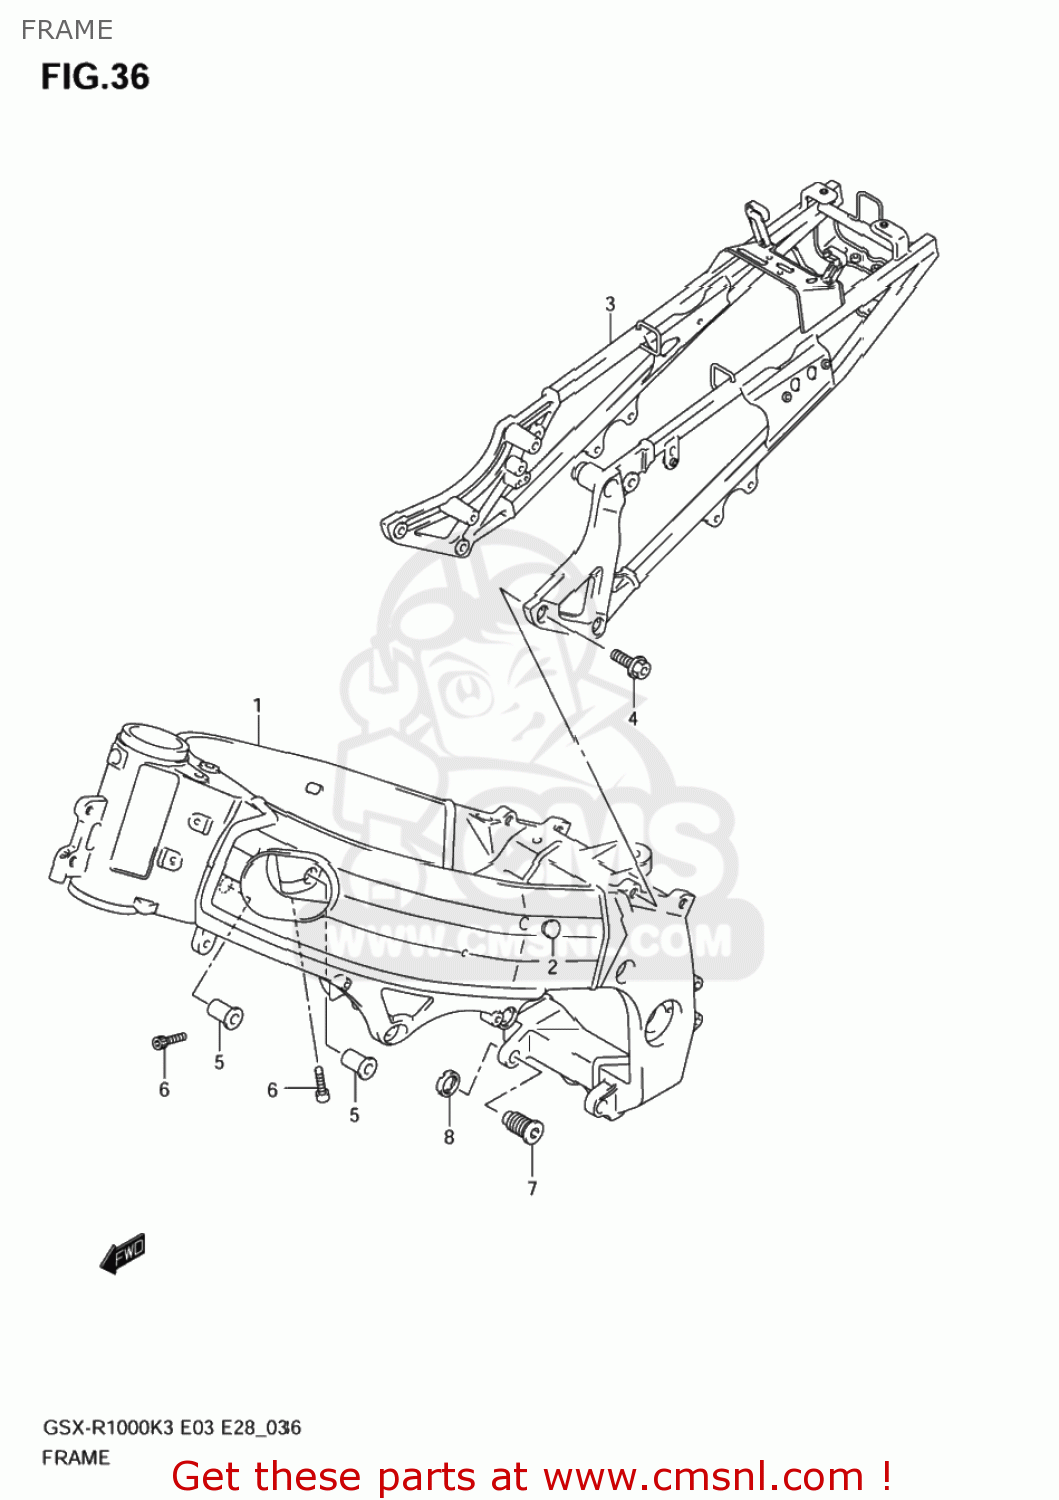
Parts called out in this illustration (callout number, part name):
1	FRAME COMP
2	CAP,TANK RAIL
3	RAIL,SEAT(BLACK)
4	BOLT,SEAT RAIL
5	SPACER,ENGINE MOUNTING
6	BOLT
7	BOLT,CRANK CASE ADJUST
8	NUT,ADJUST BOLT
